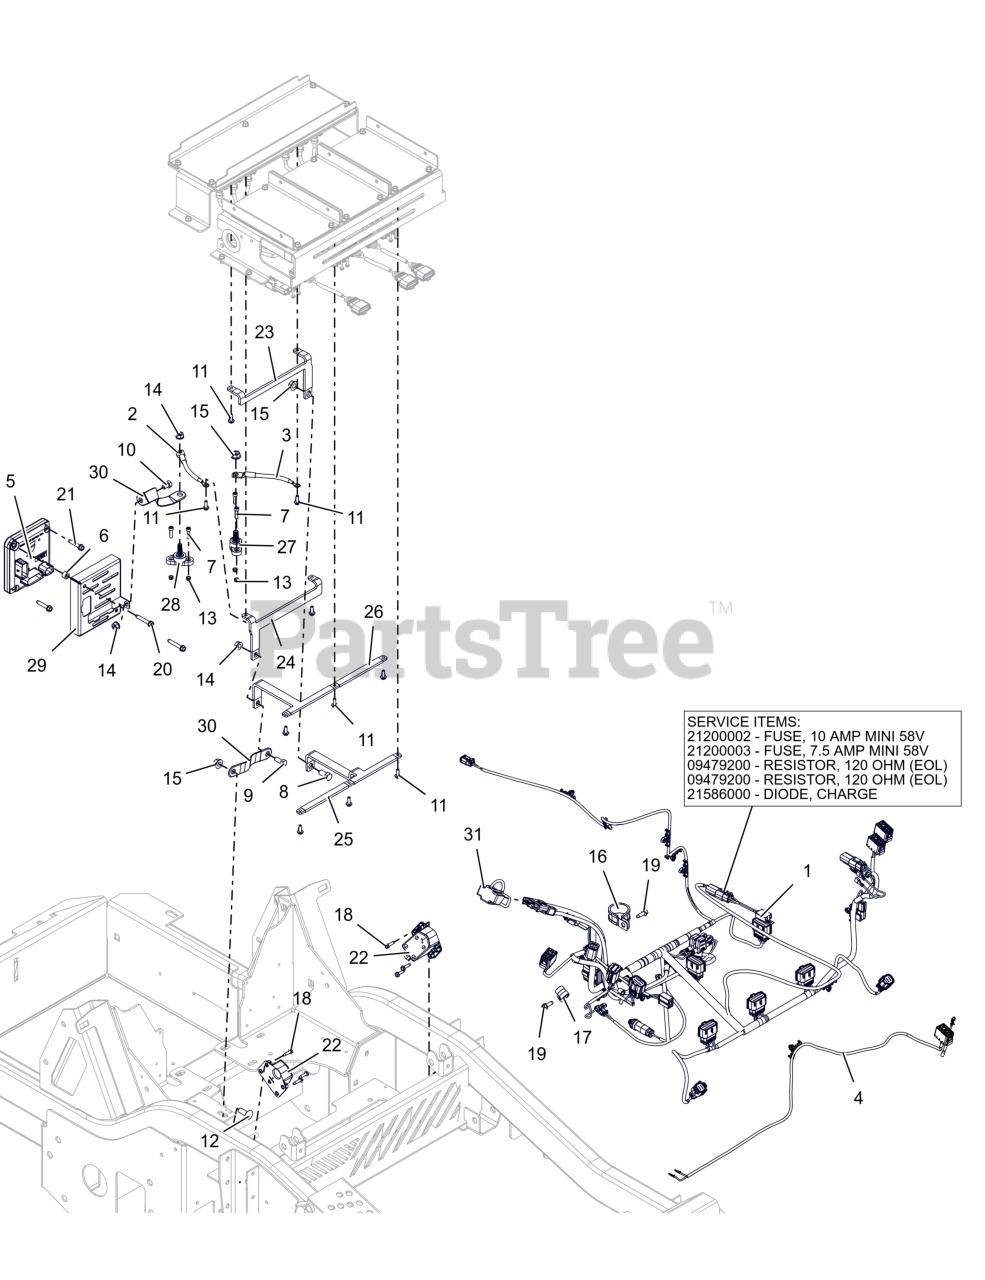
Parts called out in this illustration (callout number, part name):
1	HARNESS- PTEV MAIN WIRE
1	FUSE, 10 AMP MINI 58V
1	FUSE, 7.5 AMP MINI 58V
1	EOL RESISTOR
1	DIODE, CHARGE
2	CABLE, GROUND
3	CABLE, POSITIVE
4	HARNESS- ECO MODE ACCESSORY
5	VCM, RD ASSY
6	SPCR, .334X.500X.324
7	SCR, SKH M5-.8X20 12.9ZC120
8	BLT,HEX .38-16X.75 G5 ZCC
9	BLT,HEX .31-18X.75 G5 ZCC
10	BLT, HEX .31-18X.50 GR5 ZCC
11	BLT,HEX M5-.8X16 EP30 G8.8 ZCC
12	BLT,RHSSN .38-16X1.00 G5 ZCC
13	NUT,NYL M5-.8 G8.8 ZCC
14	NUT,LK-CTR-FLG .31-18 GF ZCC
15	NUT-LK-CTR-FLG .375-16 GF ZCC
16	CLAMP, CUSHIONED STEEL 1.25
17	CLAMP, CUSHIONED STEEL
18	SCR, TAP #10-24X.75 HWH ZCC
19	SCR,TAP .25-20X.75 HWH TR ZCC
20	SCR-TAP .25-20X1.50 HWH ZCC
21	SCR-TAP .25-20X1.25 HWH ZCC
22	SENSOR, STEERING
23	BAR, BUSS -POS. WHL
24	BAR, BUSS-NEG. WHL
25	BAR, BUSS-POS
26	BAR, BUSS -NEG
27	STUD, POSITIVE POWER
28	STUD, NEGATIVE POWER
29	COVER, VCMA ALUMINUM
30	STRAP, GROUND
31	COVER, CONNECTOR DUST
